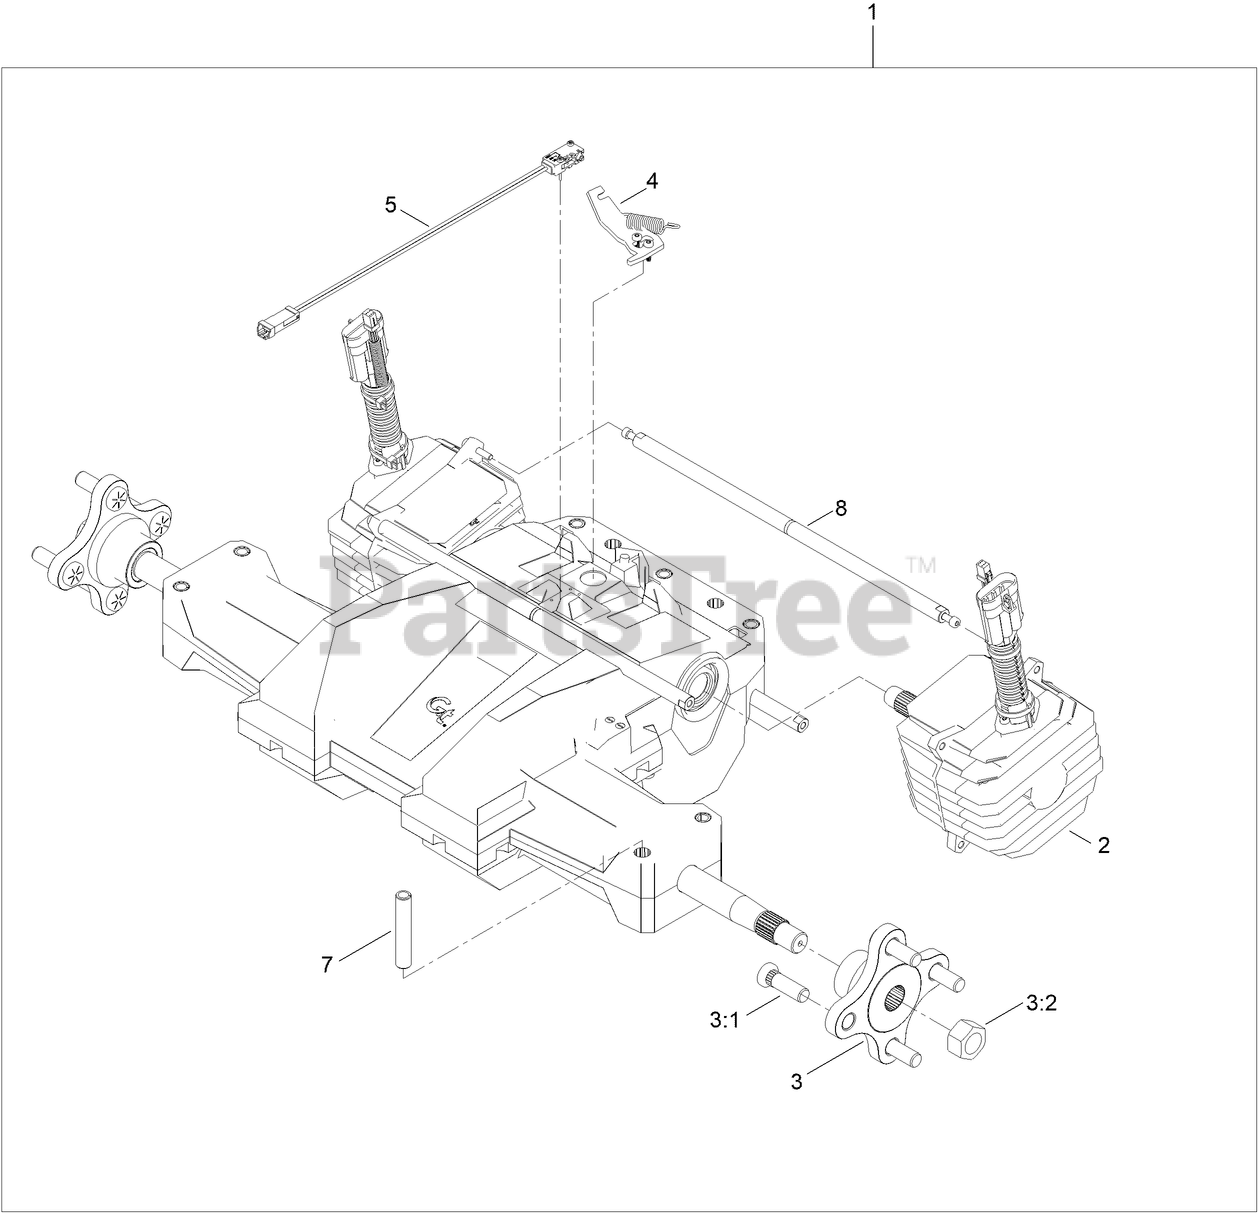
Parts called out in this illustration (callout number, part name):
1	TRANSAXLE-ELECTRIC,18" TIRE
2	MOTOR ASM [SERVICE]
3	WHEEL HUB ASM
3:1	STUD-WHEEL
3:2	NUT-HUB
4	ARM-BRAKE ASM
5	SWITCH-BRAKE ASM
7	SPACER
8	ROD-CROSS
